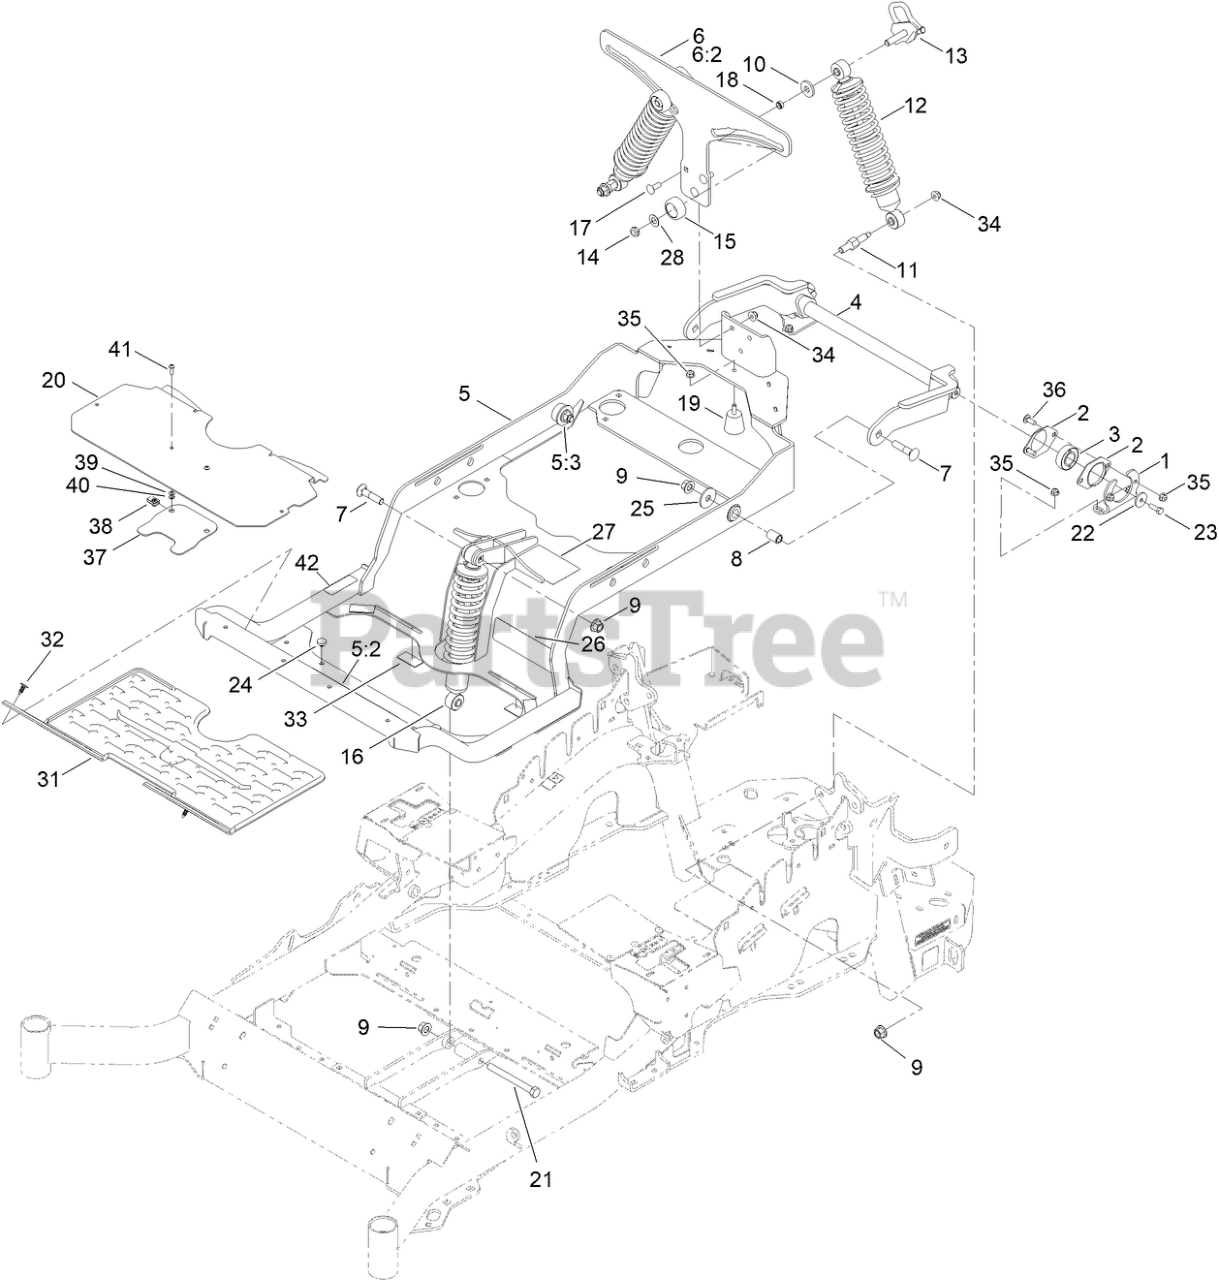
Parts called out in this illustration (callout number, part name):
1	BRACKET-BEARING
2	HOUSING-BEARING, FLANGE
3	BEARING
4	ARM-TRAILING
5	SUBFRAME ASM
5:2	DECAL-DANGER
5:3	BUSHING-FLANGE
6	BRACKET-MOUNTING
6:2	DECAL-ADJUSTMENT, RIDE
7	SCREW-CARR
8	SPACER-ALUMINUM
9	NUT-LOCK
10	WASHER-PLASTIC
11	BOLT-SHOULDER
12	SHOCK/SPRING ASM
13	CAM LOCK ASM
14	NUT-HEX
15	KNOB-LOCK, CAM
16	SHOCK ASM-FRONT
16	SHOCK/SPRING ASM
17	SCREW-CARR
18	BEARING-SLEEVE
19	BUMPER-RUBBER
20	FLOORPAN
21	SCREW-HH
22	WASHER-FLAT
23	SCREW-HH, THREAD LOCKING
24	BUMPER
25	WASHER-THRUST
26	DECAL-MYRIDE
27	DECAL-SERVICE AID
28	WASHER-ADJUSTING
31	FLOORMAT-MYRIDE
32	PLUG-PLASTIC
33	PAD-RUBBER
34	NUT-HF, NI
35	NUT-HF, NI
36	BOLT-CARR
37	ADAPTER-CAPTIVE
39	WASHER-FLAT
40	PUSHNUT-RETAINER, BOLT
41	SCREW-HSBH
42	DECAL-BRAKE, PARKING
